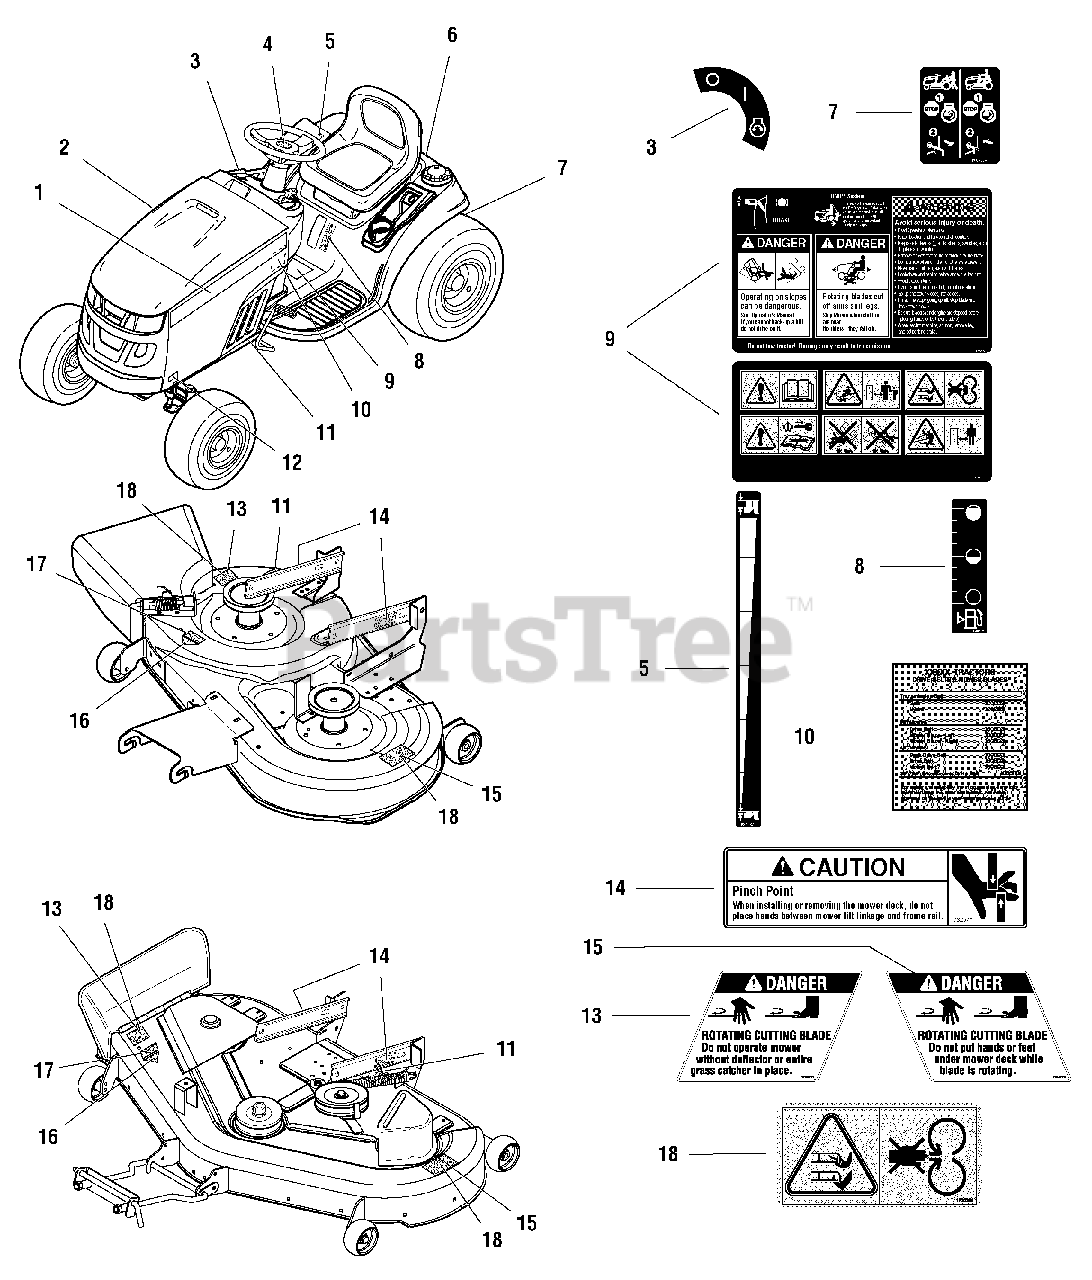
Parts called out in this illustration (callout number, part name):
1	DECAL, Snapper, LH Hood Stripe
1	DECAL, Snapper Turtle, Hood
2	DECAL, Snapper, RH Hood Stripe
3	DECAL, Ignition Switch Symbol, White/Black
4	DECAL, Steering Wheel Icon
5	DECAL, Height of Cut
6	DECAL, Snapper Rear Stripe, Silver/ 8.5LG
6	DECAL, Snapper Rear
6	DECAL, Logo, 7.88"
7	DECAL, Transmission Tow/ Release Lever
8	DECAL, Fuel Level
9	DECAL, Tunnel
9	DECAL, Safety Instructions
10	DECAL, Belts,Blades
10	DECAL, Belts, Blades
11	* DECAL, ID Plate
12	DECAL, LT200 18.5HP
12	DECAL, LT200 20HP
12	DECAL, LT200 22HP
12	DECAL, Model, ELT19546
13	DECAL, Danger, Chute in Place
13	DECAL, Danger, Discharge
14	DECAL, Pinch Point
15	DECAL, Danger, Hand Under Deck
16	* DECAL, OPEI
17	DECAL, 38"
17	DECAL, 42"
17	DECAL, 44"
17	DECAL, 46"
17	DECAL, 50"
18	DECAL, Hand Under Deck
18	DECAL, Danger, Mower Deck
